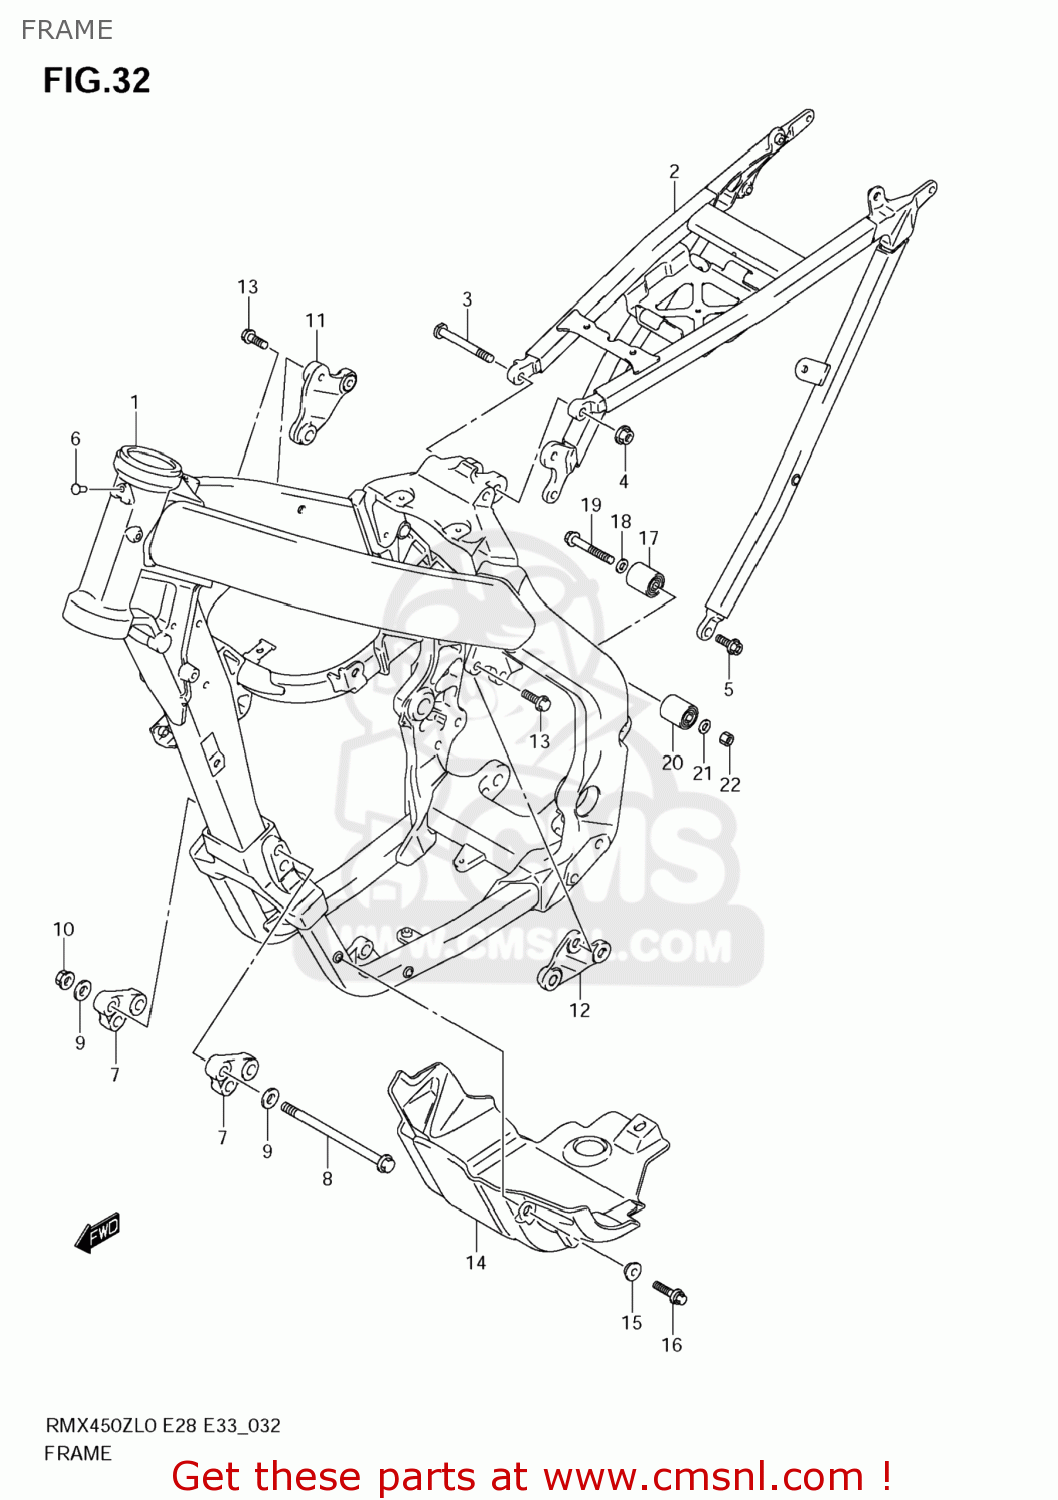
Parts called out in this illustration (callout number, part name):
1	FRAME
2	RAIL,SEAT
3	BOLT,SEAT RAIL UPR
4	NUT
5	BOLT(8X20)
6	CAP(OD:10)
7	BRACKET,ENGINE MOUNTING FR
8	BOLT(10X120)
9	WASHER(10.5X22X2.3)
10	NUT
11	BRACKET,ENGINE MOUNTING UPR,R
12	BRACKET,ENGINE MOUNTING UPR,L
13	BOLT(8X21)
14	PROTECTOR,ENGINE
15	WASHER,ENGINE PROTECTOR
16	BOLT(6X25)
17	ROLLER,CHAIN
18	SHIM(8X16X1)
19	BOLT(8X45)
20	ROLLER,CHAIN
21	SHIM(8X12X1)
22	NUT
